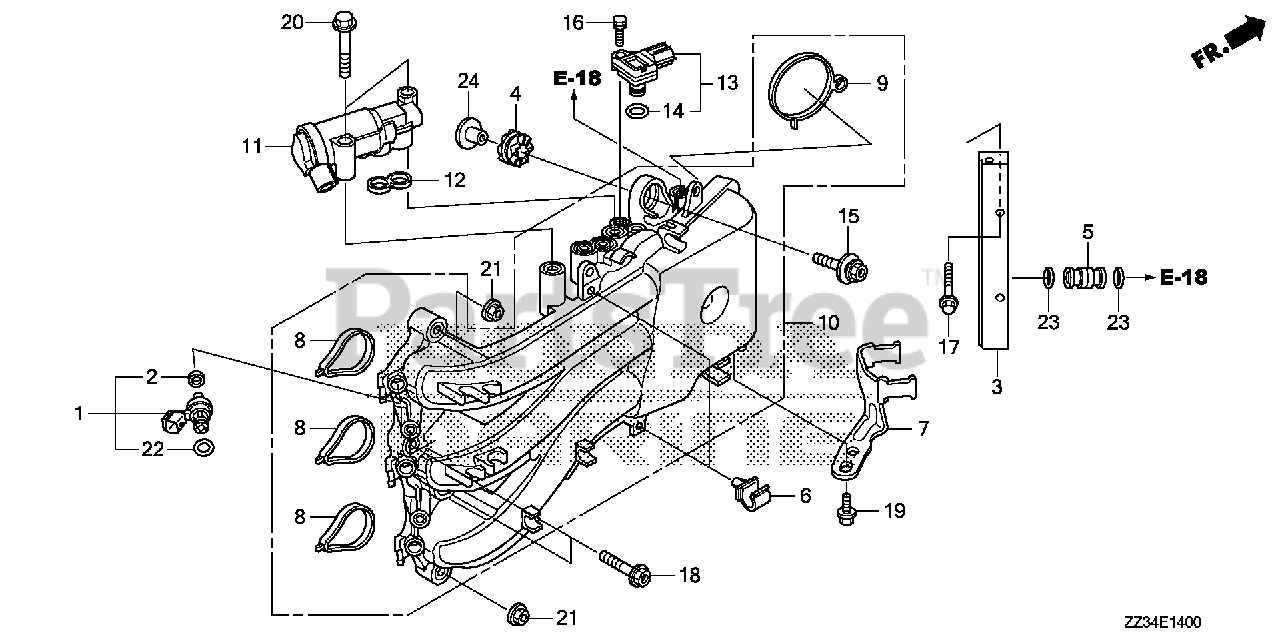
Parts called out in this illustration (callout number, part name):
1	INJECTOR ASSY., FUEL
2	RING, SEAL
3	LINE, FUEL
4	GROMMET, VAPOR SEPARATOR
5	JOINT, FUEL PIPE
6	CLAMP B, FUEL TUBE
7	STAY, FUEL STRAINER
8	GASKET, IN. MANIFOLD
9	GASKET, THROTTLE BODY
10	MANIFOLD, INLET
11	VALVE ASSY., ELECTRONIC AIR CONTROL
12	GASKET, ELECTRONIC AIR CONTROL VALVE
13	SENSOR ASSY., MAP
15	BOLT-WASHER (8X35)
16	BOLT-WASHER (5X18)
17	BOLT, FLANGE (6X32)
18	BOLT, FLANGE (8X32)
19	BOLT, FLANGE (6X12)
20	BOLT, FLANGE (8X45)
21	NUT, FLANGE (8MM)
22	O-RING (7.3X2.2)
23	O-RING (7.8X1.9) (ARAI)
24	COLLAR (8.5X14.5)
